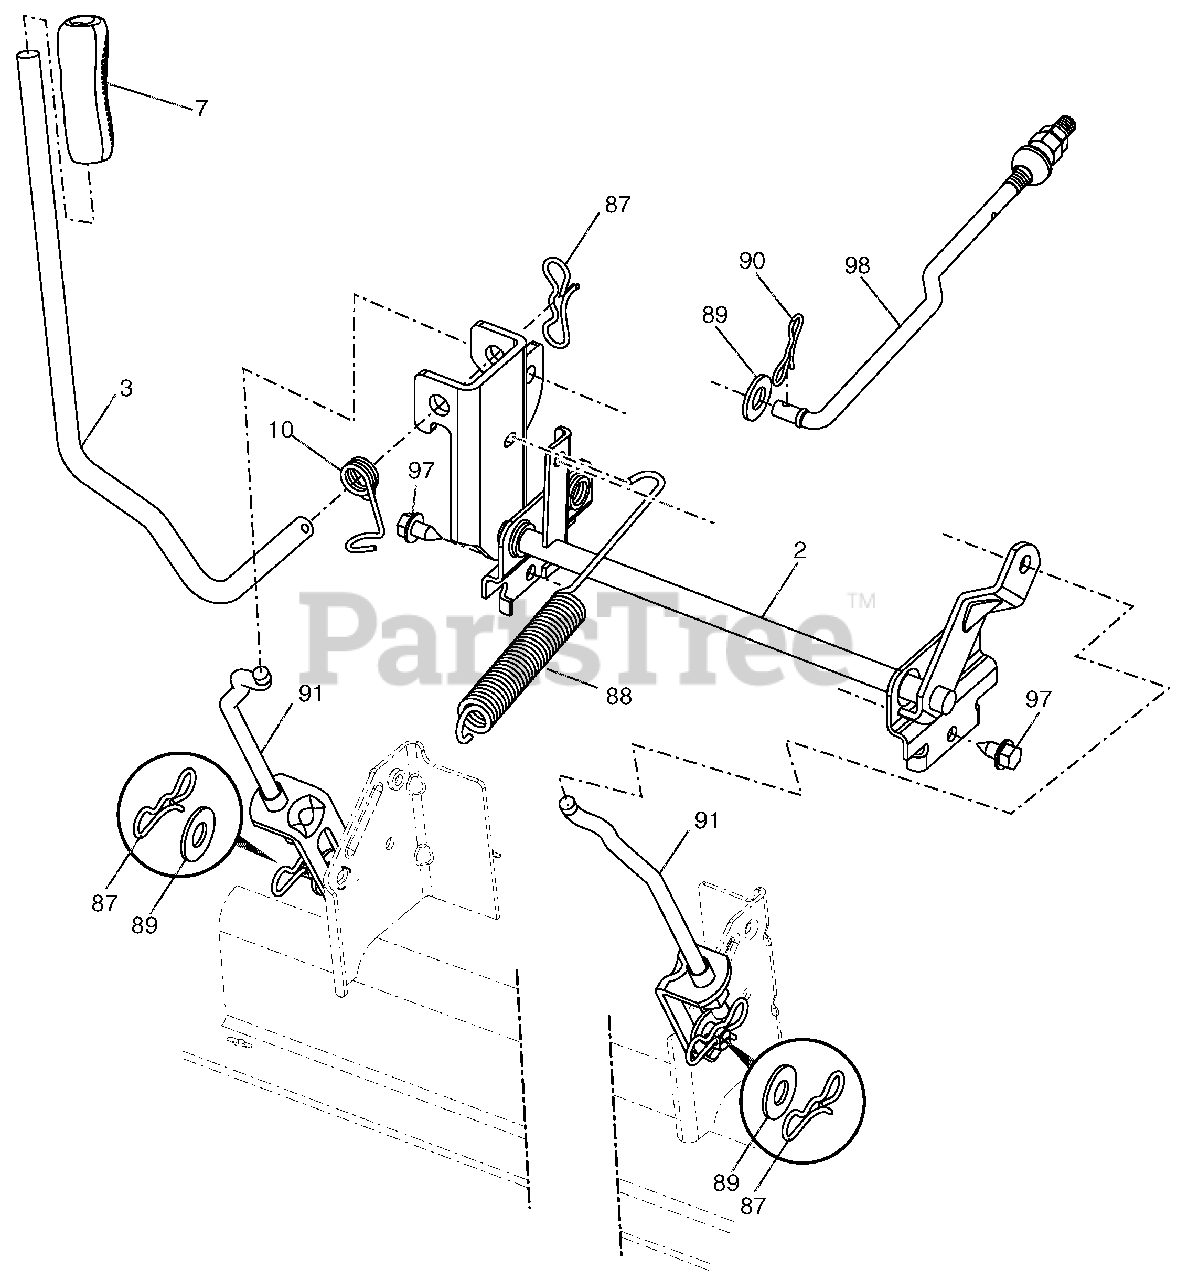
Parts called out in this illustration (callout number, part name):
2	SHAFT ASM., LIFT
3	LEVER.LIFT.HANDLE.LT
7	GRIP LEVER 5625 LD BLACK 428
10	SPRING.TORSION.HANDLE.LIFT
87	PIN.COTTER.7/16.BOW TIE LOCK
88	SPRING.LIFT ASSIST
89	WASHER.CLEAR ZINC
90	PIN.COTTER.5/16.BOW TIE LOCK
91	LINK.LIFT.SUSP.MOWER.REAR
97	SCREW.HEXWSH THDR3/8-16X3/4.BL
98	LINK.LIFT.SUSP.MOWER.FRONT
